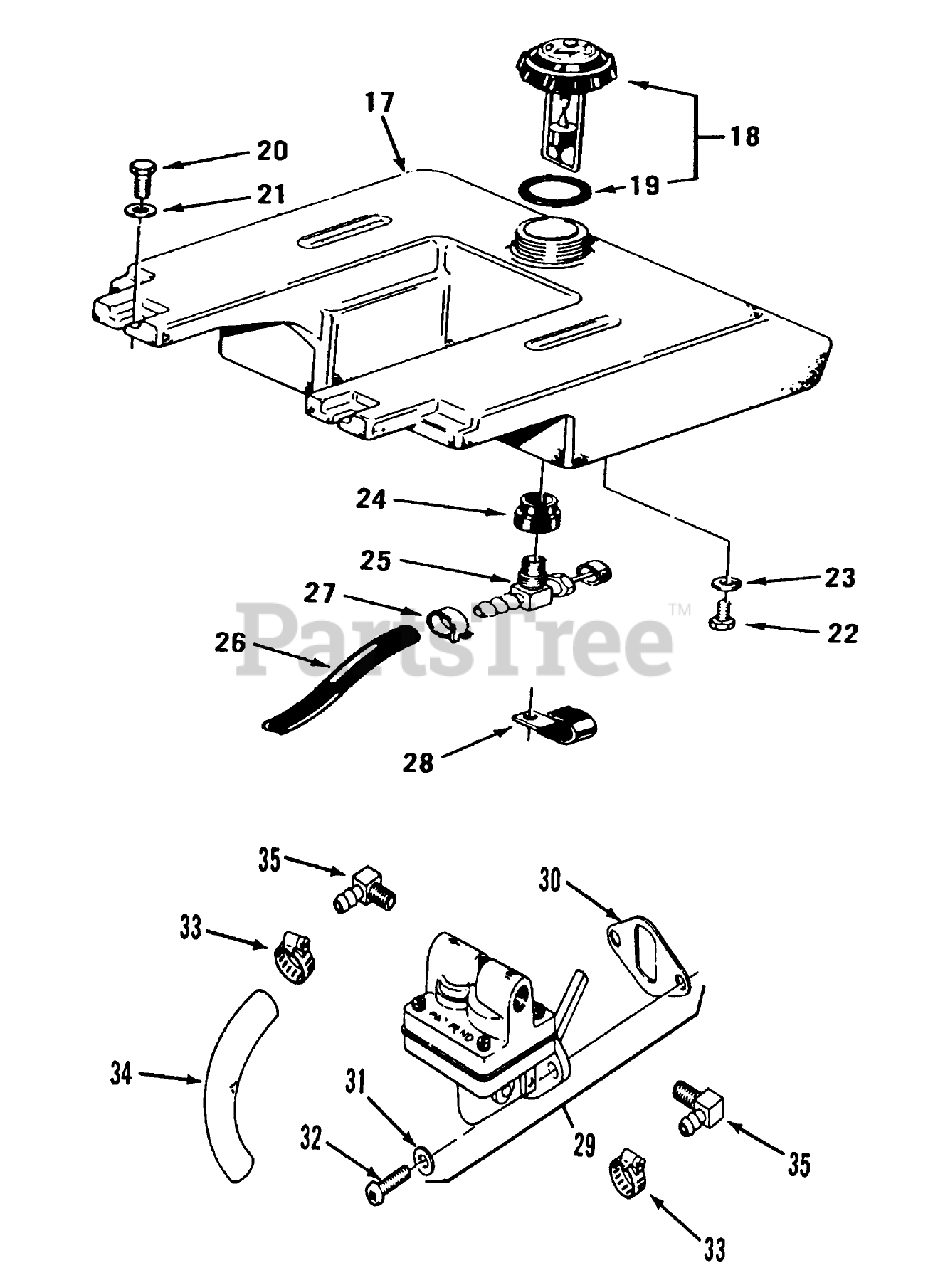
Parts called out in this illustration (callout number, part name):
17	TANK-FUEL
18	ASSY-GAUGE CAP
25	VALVE-FUEL
28	CLAMP
29	KOHLER 47-559-08
30	KOHLER 25-041-05
31	KOHLER X-159-2
32	KOHLER X-174-2
33	KOHLER X-426-9
34	KOHLER 25-353-01
35	KOHLER 25-155-02
